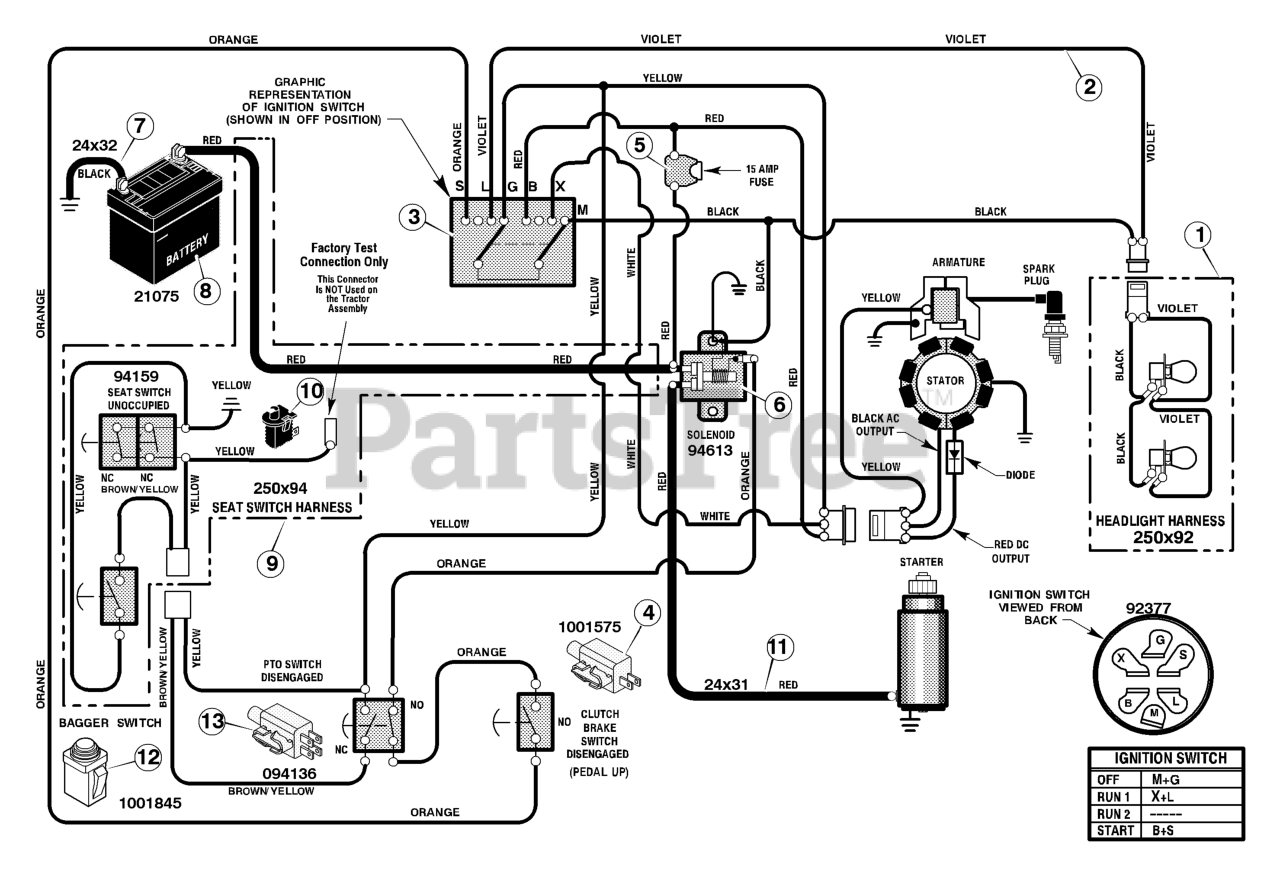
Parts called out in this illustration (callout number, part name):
1	Harness, Light Wire
2	Harness, Chassis Wire
3	Switch, Ignition
4	Switch, Limit
6	Solenoid
7	CABLE, Battery Ground
8	Battery
9	Harness, Seat Switch Wire
10	Switch, Seat Sensor
12	Switch, Bag Sensor
13	Switch, Limit
